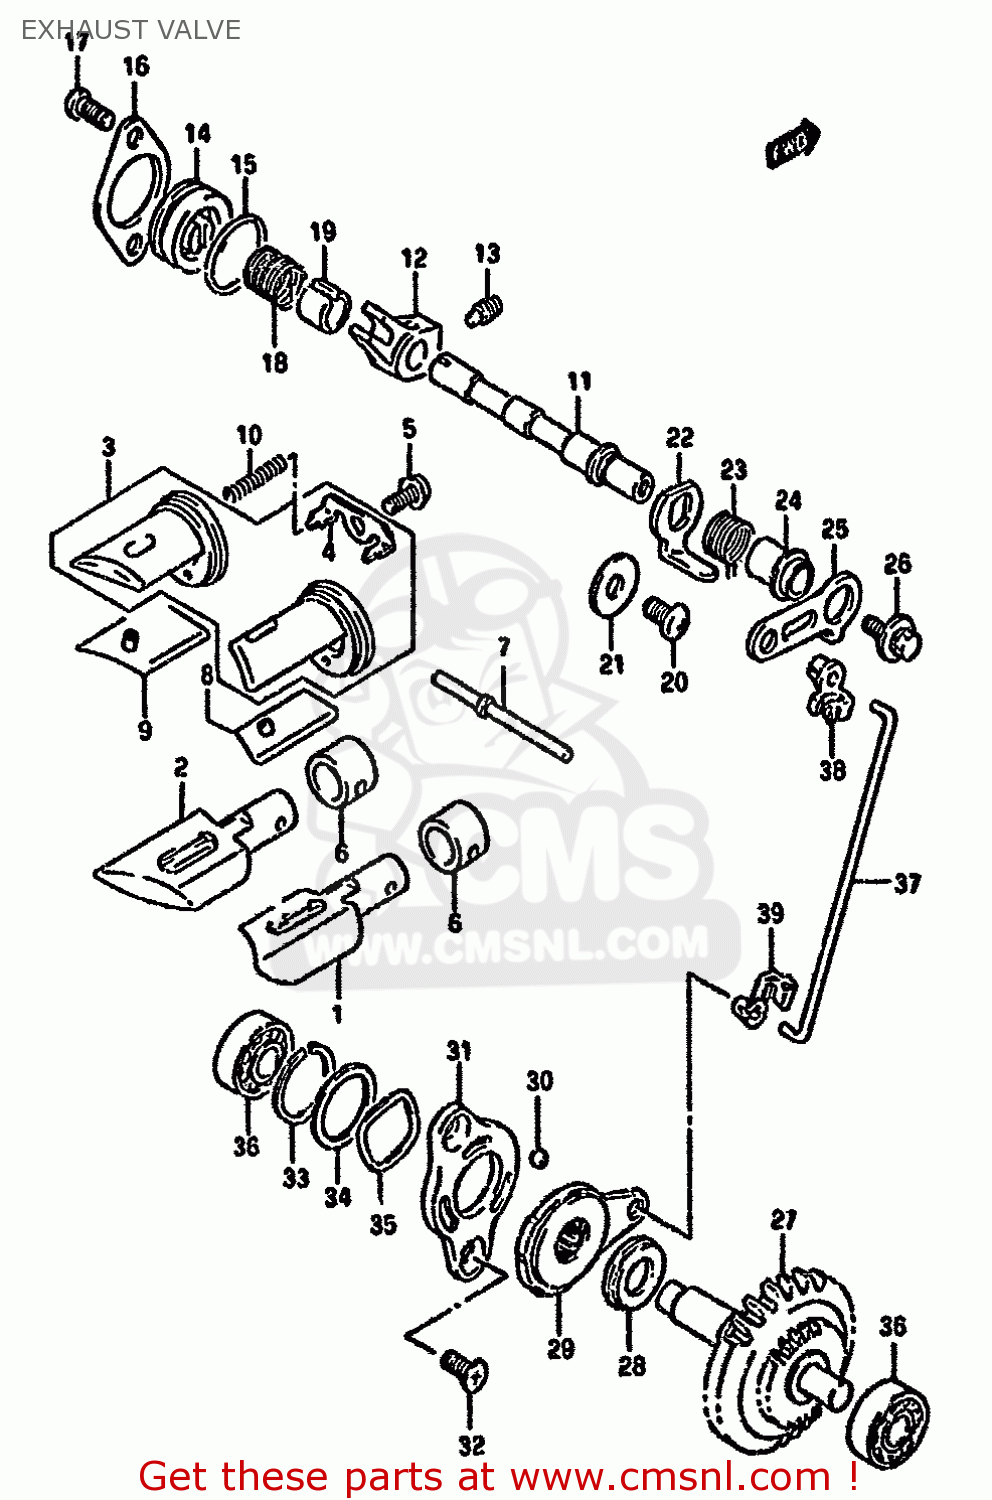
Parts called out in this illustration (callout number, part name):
1	VALVE,EXHAUST,LOWER,RIGHT
2	VALVE,EXHAUST LOW,L
3	GUIDE SET,EXHAUST VALVE
4	STOPPER,EXHAUST VALVE
5	SCREW
6	SPACER,EXHAUST VALVE
7	PIN,EXHAUST VALVE 48.5MM
8	VALVE,EXHAUST MIDDLE RH
9	VALVE,EXHAUST MIDDLE LH
10	SPRING
11	SHAFT,EXHAUST VALVE
12	ARM,EXHAUST VALVE SHAFT
13	SCREW(6X10)
14	CAP,EXHAUST VALVE
15	O RING(D:1.9,ID:22.6)
16	RETAINER,EXHAUST VALVE
17	BOLT
18	SPRING
19	SPACER,EXHAUST VALVE SPRING
20	BOLT
21	WASHER
22	LEVER,EXHAUST VALVE NO.2
23	SPRING
24	SPACER,EXHAUST VALVE
25	LEVER,EXHAUST VALVE NO.1
26	BOLT(5X12)
27	GOVERNOR ASSY,EXHAUST VALVE
28	BEARING(10X22X2.8)
29	ACTUATOR,EXHAUST VALVE
30	BALL
31	STARTER,EXHAUST VALVE ACTUATOR
32	SCREW(5X10)
33	CIRCLIP
34	SHIM(19.1X25X0.3)
35	WASHER
36	BEARING(8X22X7)
37	ROD,EXHAUST VALVE
38	BUSH,EXHAUST VALVE ROD NO.1
39	BUSH,EXHAUST VALVE ROD NO.2
